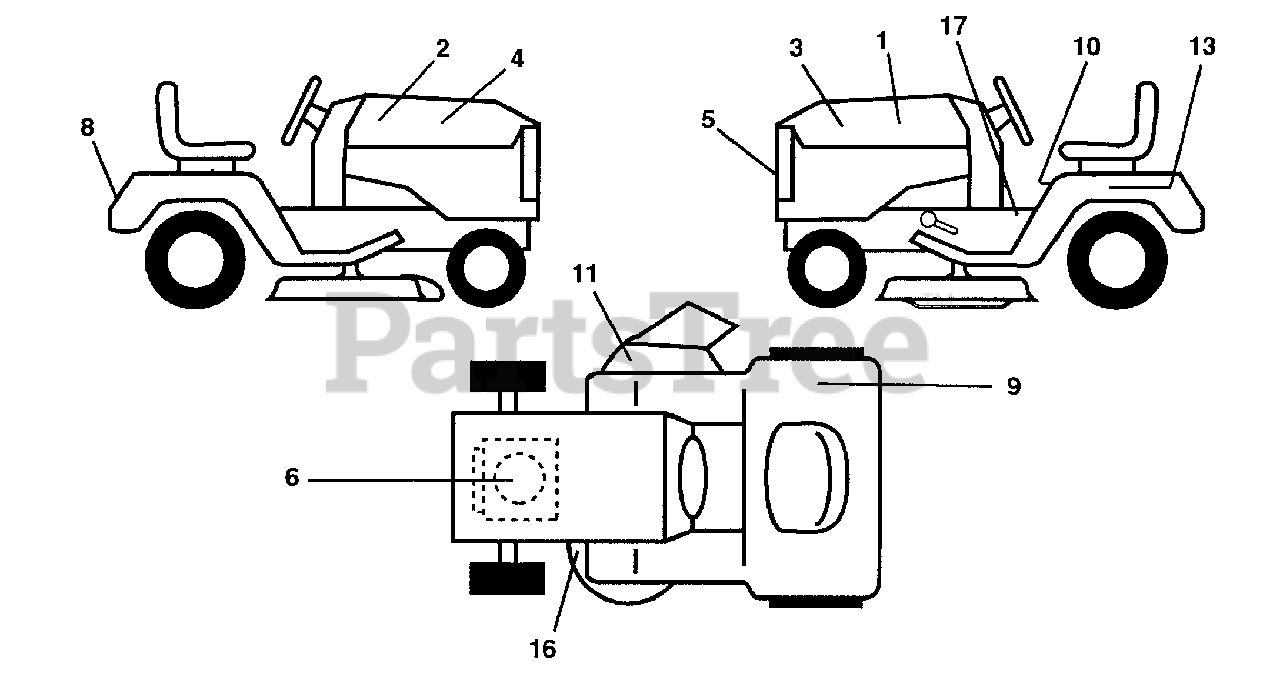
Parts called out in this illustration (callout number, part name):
1	Decal, Hood, L. H., Husqv.
2	Decal, Hood, R. H., Husqv.
3	Decal, Hood, L. H., LR120
4	Decal, Hood, R. H., LR120
5	Decal, Logo, Grill
6	Decal, Engine
8	Decal, Logo, Fender
9	Decal, Certification, (French/Dutch)
10	Decal Caution Fender
11	Decal, Warning, Cut Finger, (Multi-Lang)
13	Decal, Caution, Battery
16	Decal, V-Belt Sch.
17	Decal, Inst. Oper.
